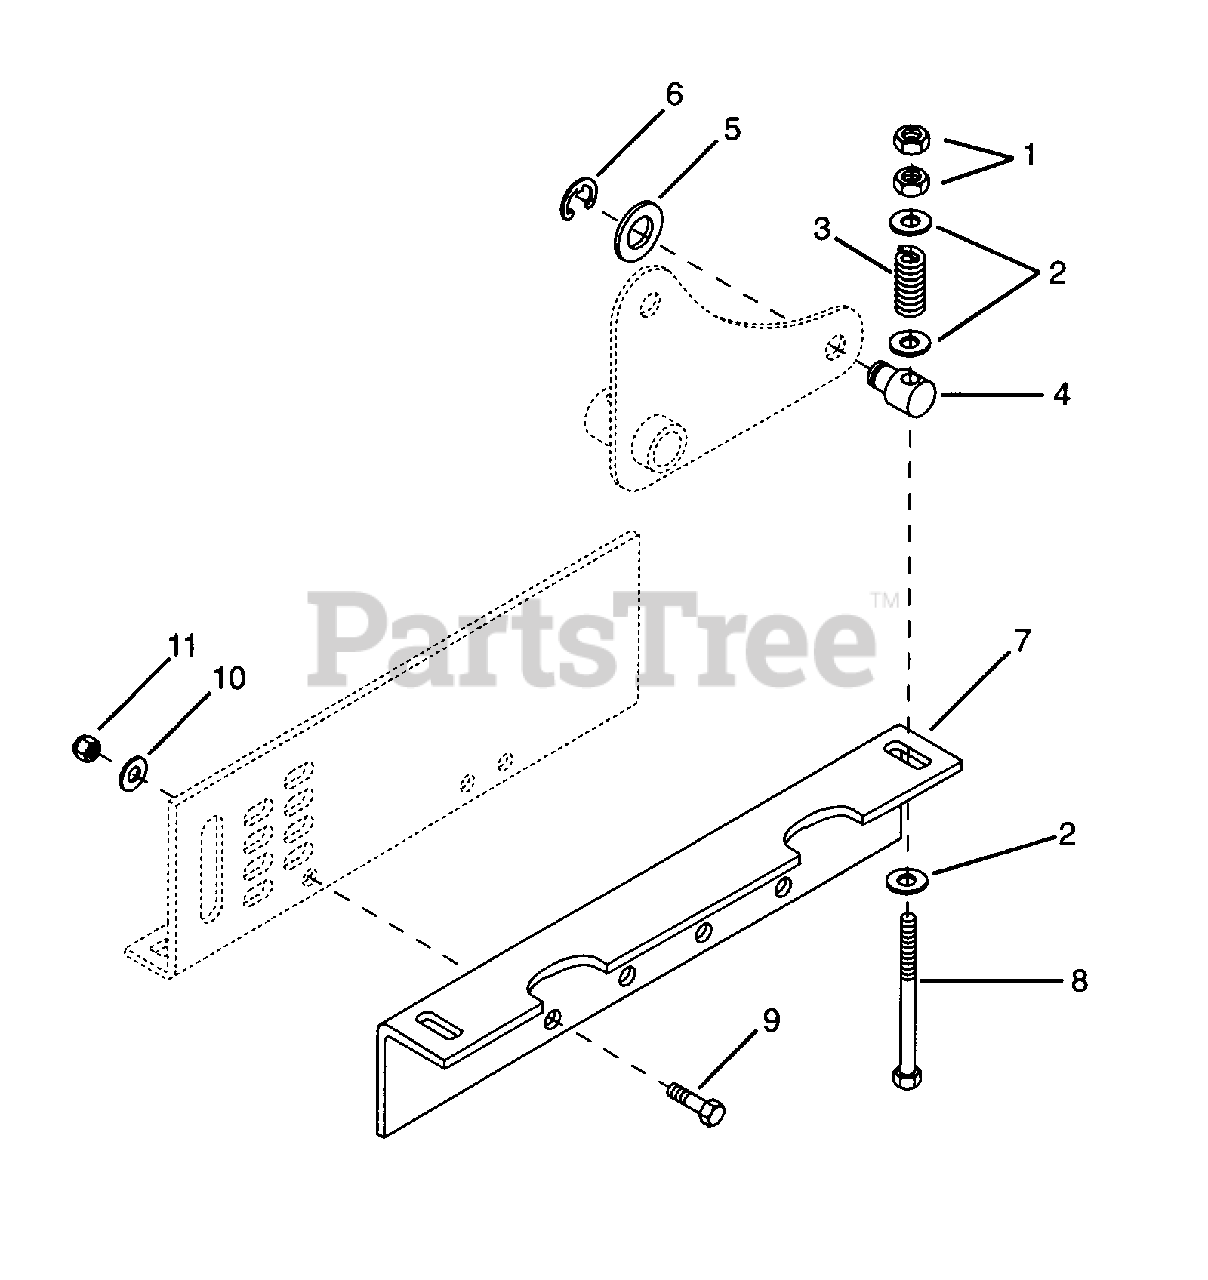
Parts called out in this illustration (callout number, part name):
1	Nut-Jam .50-13 Grade 2
2	Washer-Flat-Steel .563 x 1.375 x .109
3	Spring-Compression .125 x .78 x 1.00
4	Pivot, Mower Lift
5	Washer-Flat-Steel .656 x 1.625 x .188
6	Ring-Retaining-External .750 x .050
7	Lift Bracket
8	Bolt-Hex .50-13 x 6.50
9	Bolt-Hex .38-16 x 1.50 Grade 5
10	Washer-Flat-Steel .438 x 1.0 x .083
11	Nut-Locking-Nylon .375-16 Grade 2
